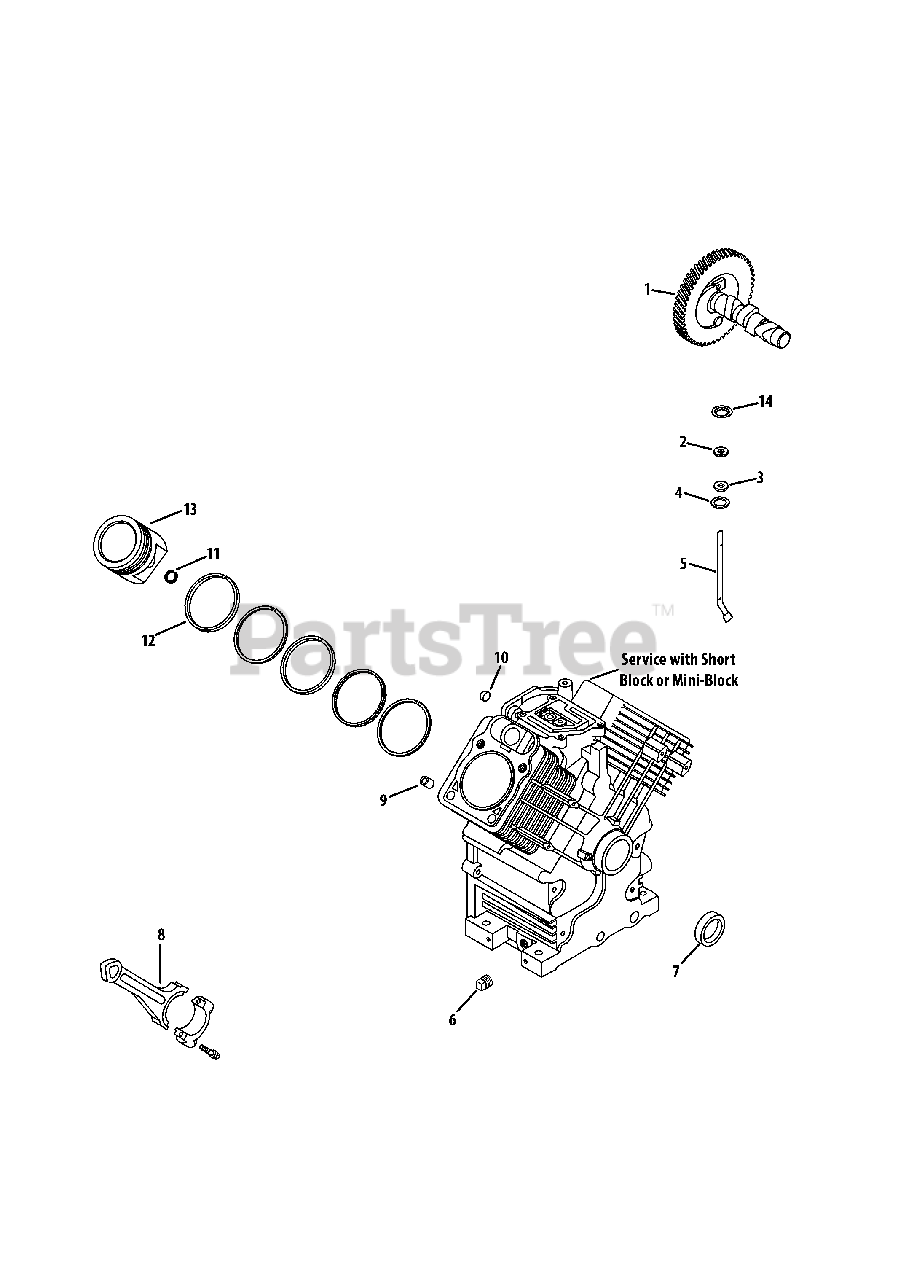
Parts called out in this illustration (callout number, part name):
1	Camshaft Kit
2	Flat Washer, 9 MM
3	Governor Cross Shaft Seal
4	Flat Washer, 11/32
5	Governor Cross Shaft
6	Square Headd Pipe Plug, 3/8
7	Oil Seal (Helix Lip)
8	Connecting Rod Assembly
11	Piston Pin Retainer
12	Ring Set (Std)
12	Ring Set (.08)
12	Ring Set (.25)
12	Ring Set (.50)
13	Piston Assembly Kit w/ Ring (Std.) 77MM
13	Piston Assembly Kit w/ Ring Set (.08) 77MM
13	Piston Assembly Kit w/Ring Set (.25) 77MM
13	Piston Assembly Kit w/ Ring Set (.5) 77MM
14	Ring Retainer
